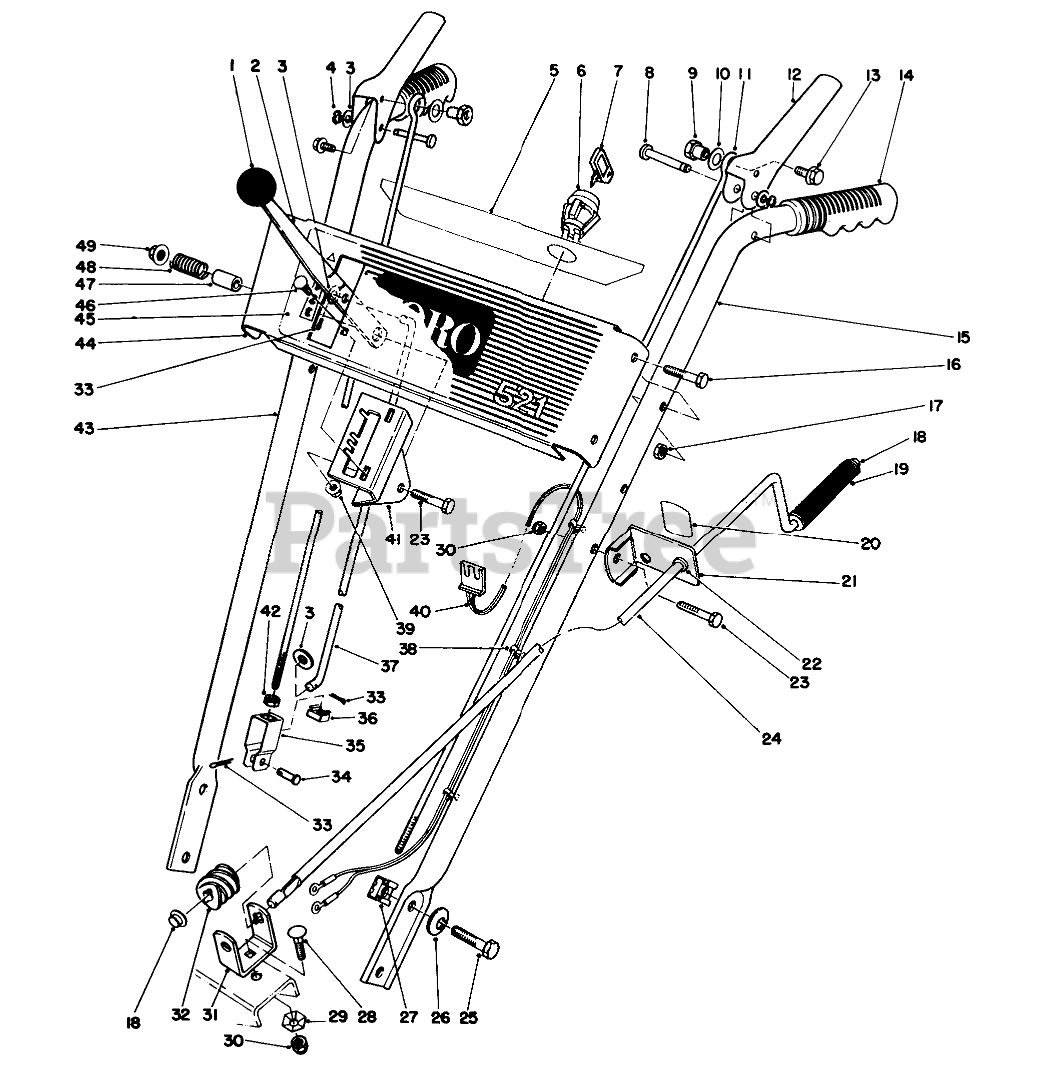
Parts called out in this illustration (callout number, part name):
2	SPEED SELECTOR B
3	WASHER-PLAIN
4	RING-CLIP
5	DECAL - ESCUTCHEON BACK
6	SWITCH
7	KEY-IGNITION
8	PIN-LEVER, CONTROL
9	POST-MOUNTING, LINKAGE
10	WASHER-FLAT
11	LINK-UPPER
12	HANDLE-CONTROL
13	SCREW-HHF
14	GRIP-HANDLE
15	LEFT HANDLE
16	SCREW-HH
17	NUT-LOCK, NI
18	RETAINER-PUSH ON
19	Grip-Rod
20	DECAL-CHUTE DIRECTION
21	BRACKET W/DECAL
22	Bushing
23	SCREW-HH
24	ROD-CONTROL, CHUTE
25	SCREW-HH
26	WASHER-BELLEVILLE
28	BOLT-CARR
29	WASHER-LOCK
30	NUT-LOCK, NI
31	BRACKET-WORM
32	GEAR-WORM, CHUTE
33	PIN-COTTER
34	PIN-CLEVIS
35	CLEVIS
36	NUT-RETAINED
37	ROD-SELECTOR, SPEED
38	Mount-Wire
39	NUT-HF
40	WIRE HARNESS
41	Mount-Speed Selector
42	NUT-JAM
43	RIGHT HANDLE
44	ESCUTCHEON PLT B
45	DECAL ESCUTCHEON
46	SCREW-CARRIAGE
47	SPACER
48	SPRING
49	NUT-HF
